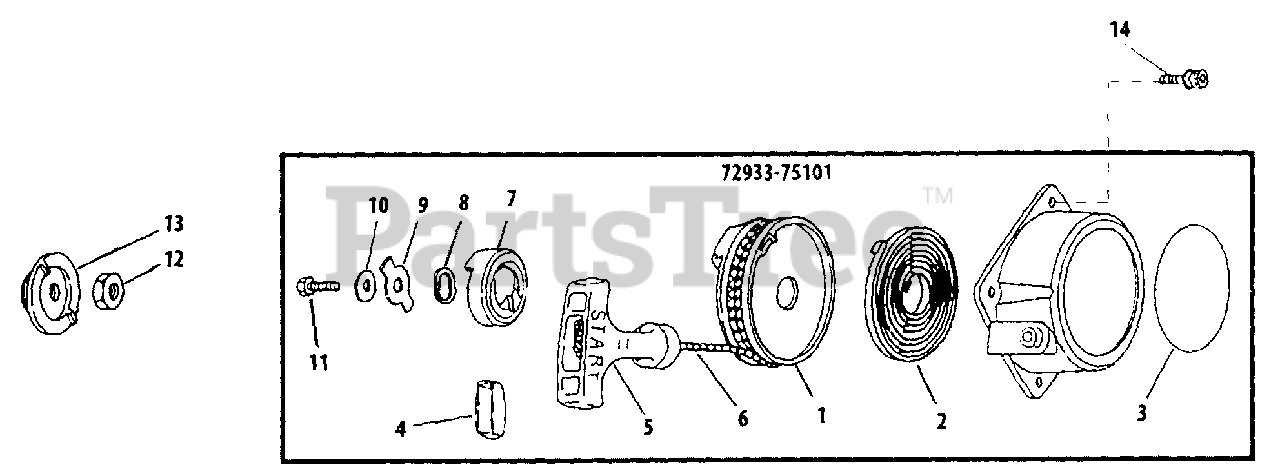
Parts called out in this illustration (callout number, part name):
1	REEL, ROPE
2	SPRING, RECOIL
3	LABEL, RECOIL STARTER
4	RETAINER, ROPE
5	HANDLE
6	ROPE, STARTER
7	RATCHET
8	WASHER, WAVE
9	RETAINER
10	WASHER 5 MM
11	SCREW 5 MM
12	NUT M8×1
13	PULLEY, STARTER
14	BOLT, ADHESIVE M4×12
72933-75101	STARTER ASSY, RECOIL
